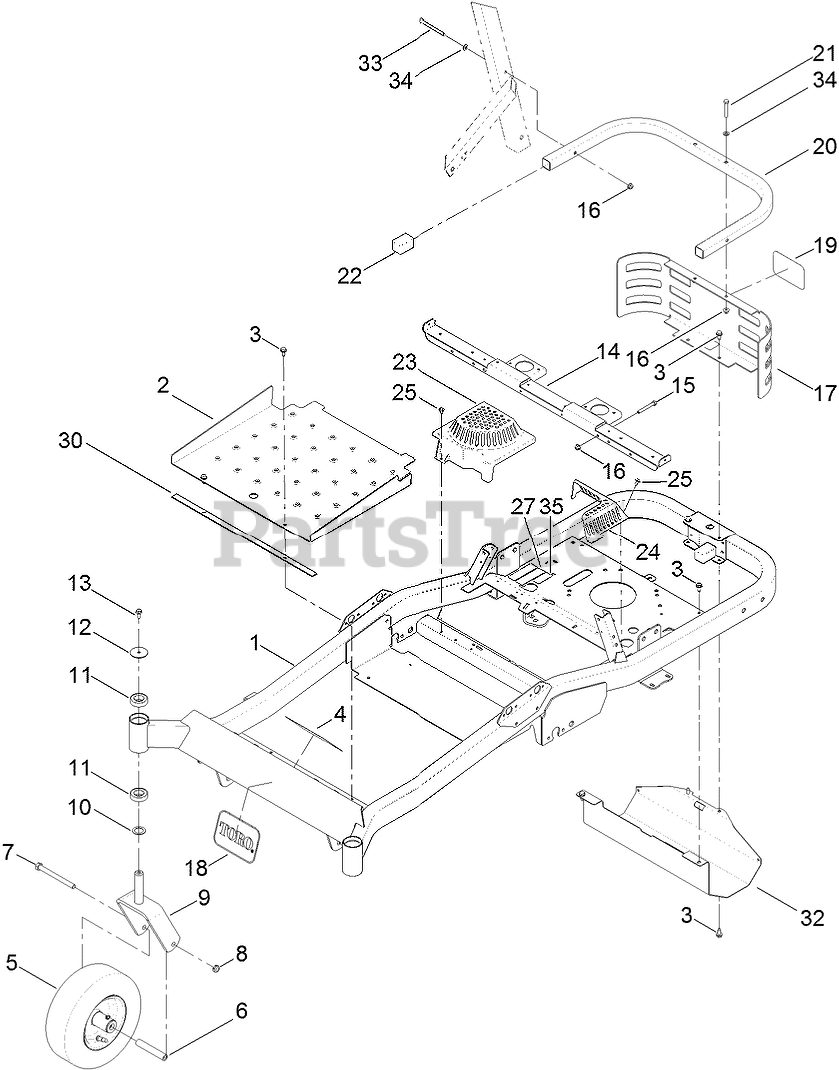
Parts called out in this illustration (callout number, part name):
2	PAN-FLOOR
3	SCREW-HWHTF
4	DECAL-SAFETY
5	WHEEL AND TIRE ASM
6	SPACER-SPANNER
7	SCREW-HH
8	NUT-LOCK, NI
9	FORK-CASTER
10	WASHER-THRUST
11	BEARING-BALL
12	WASHER
13	SCREW-HHF
14	SUPPORT-SEAT
15	SCREW-HH
16	NUT-HF, NI
17	GUARD-REAR
18	DECAL
20	TUBE-GUARD
21	SCREW-HH
23	COVER-FAN, RH
24	COVER-FAN, LH
25	SCREW-HHFTF
27	DECAL-EMISSIONS, E P A
30	STRIP-VIBRATION, ANTI
32	GUARD-MUFFLER
33	SCREW-HH
34	WASHER-PLAIN
35	DECAL-LOCATION, SERVICE DEALER
